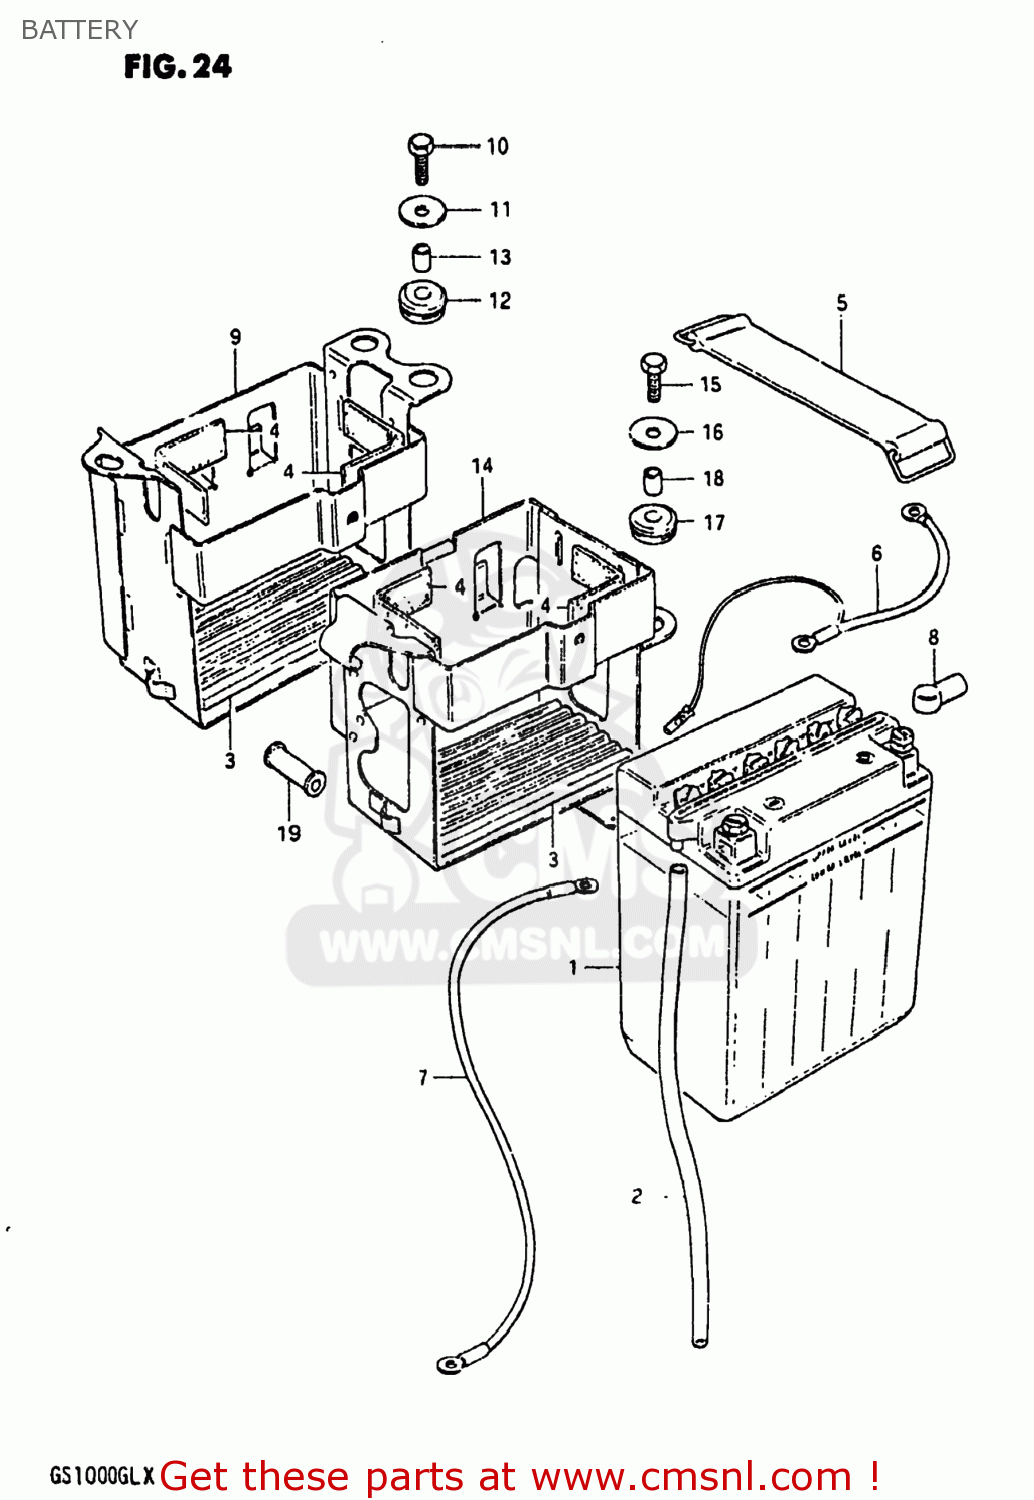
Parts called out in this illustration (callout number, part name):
1	BATTERY ASSY (12V)
2	HOSE,BATTERY EXHAUST
3	PROTECTOR,BATTERY
4	PROTECTOR(20X90)X4
5	BAND
6	WIRE,BATTERY PLUS
7	LEAD WIRE,BATTERY(-)
8	CAP,TERMINAL
9	HOLDER,BATTERY
10	BOLT, UPPER
11	WASHER
12	CUSHION
13	SPACER(6.2X8.3X5.7)
14	HOLDER,BATTERY
15	BOLT, UPPER
16	WASHER(6,5X22X1.6)
17	CUSHION
18	SPACER(6.2X8.3X5.7)
19	CUSHION
